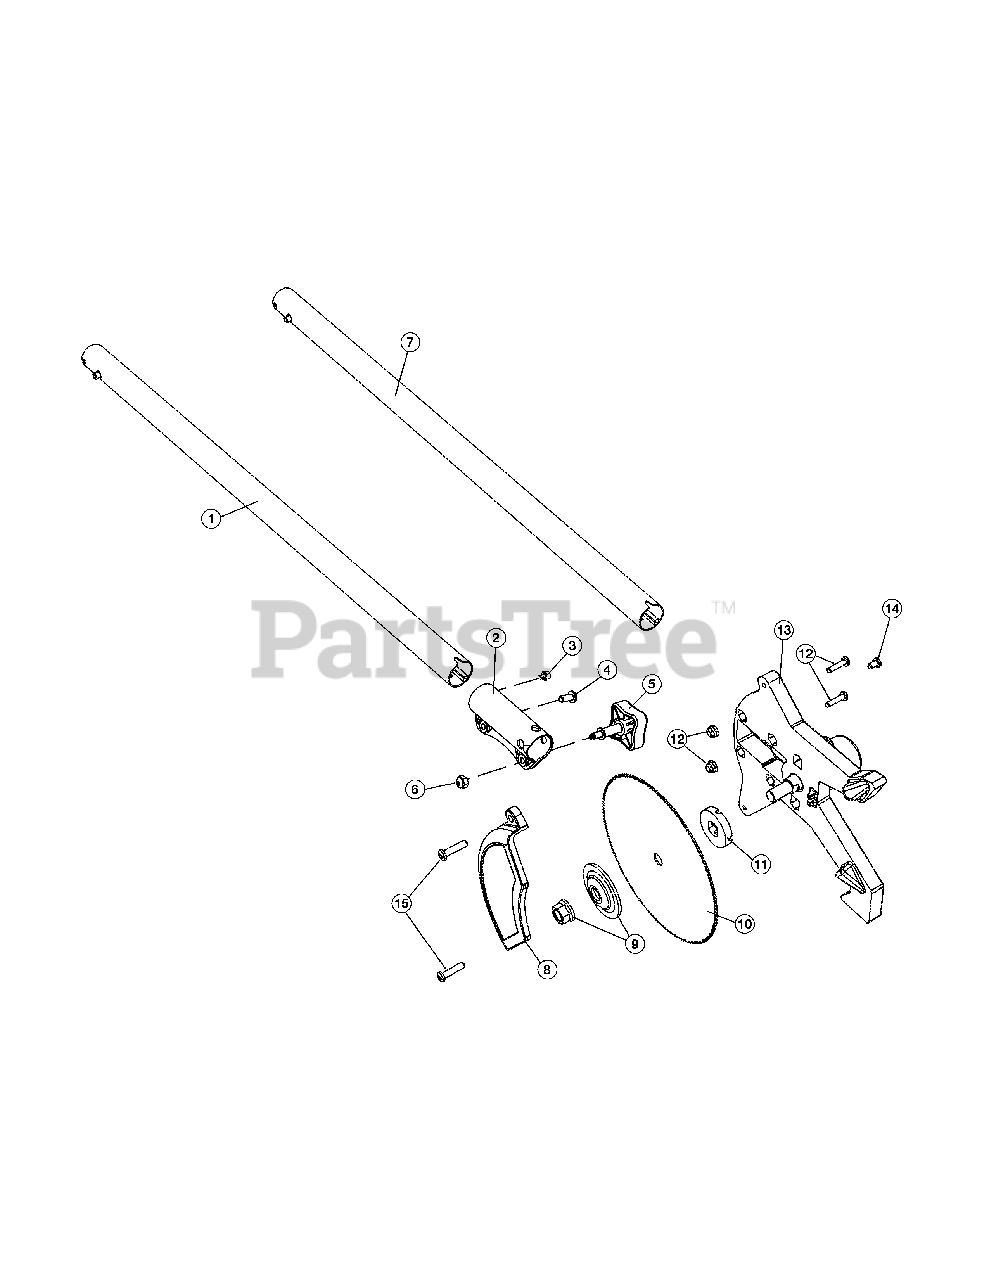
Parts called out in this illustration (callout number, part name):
1	Extension Boom
2	Split Boom Coupler
5	Adjustment Knob
6	Knob Retaining Nut
7	Drive Shaft Housing Assembly
8	Blade Cover
9	Blade Retaining Kit
11	Blade Spacer
12	Tube Mounting Hardware
13	Gearbox Assembly
14	Anti-Rotation Screw
15	Screw
